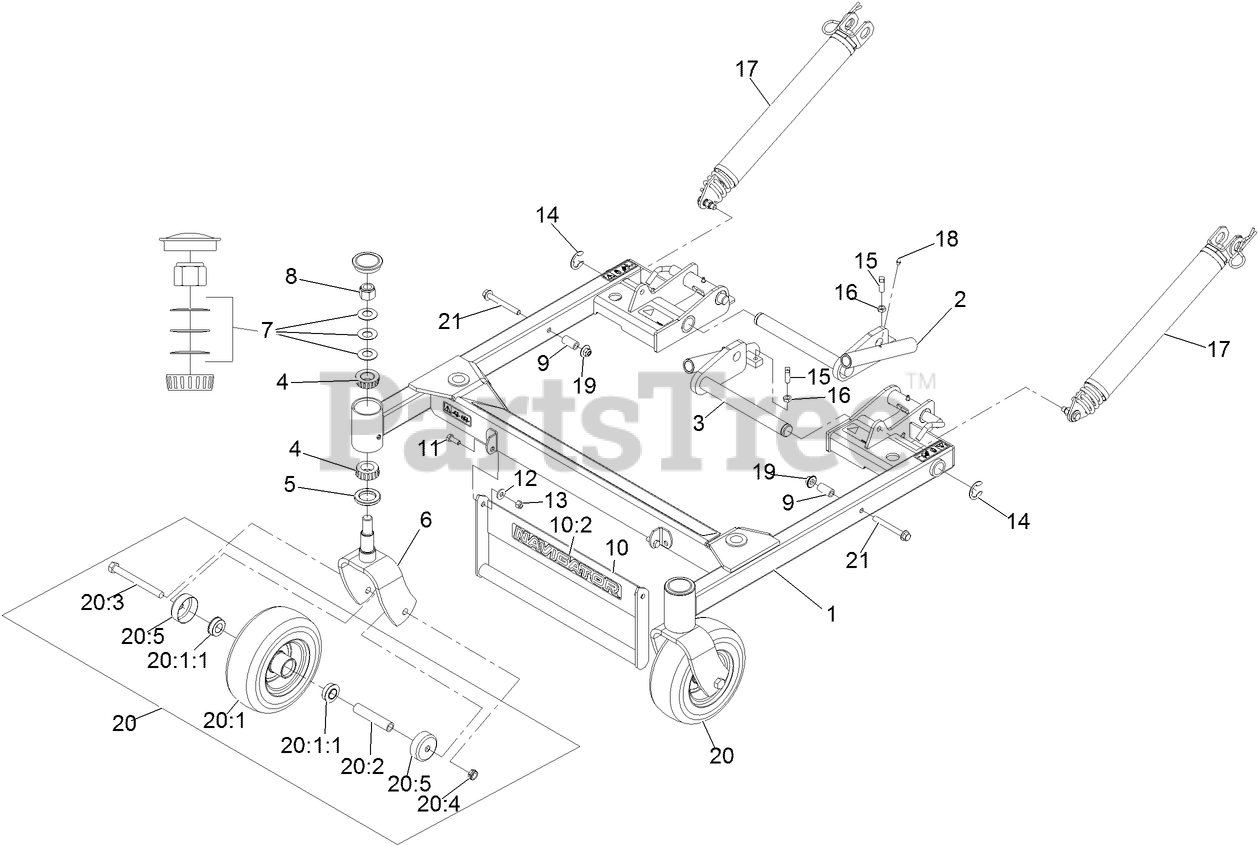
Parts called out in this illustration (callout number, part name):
1	Frame-Deck Support W/Decals
2	PIVOT-DECK, RH
3	PIVOT-DECK, LH
4	Cone-Bearing Tapered Roller
5	SEAL-GREASE
6	FORK-CASTER
7	WASHER-BELLVILLE
8	NUT-LOCK, NI
10	ASM,DECK LIFT HANDLE W/DECAL
10:2	DECAL-NAVIGATOR LOGO
11	SCREW-HH
12	WASHER-SPRING
13	NUT-LOCK, NI
14	RING-SNAP
15	SCREW-SET, SQH
16	NUT-JAM
17	LIFT ASSIST SPRING ASM
18	FITTING-GREASE
19	Nut-Nyloc 3/8-16 Flg
20	ASM,FF CASTER WHEEL W/AXLE
20:1	ASM,WHEEL AND TIRE
20:1:1	Bearing-Ball
20:2	SPACER-CASTER, FRONT
20:3	SCREW-HH
20:4	NUT-HEX
20:5	GUARD-SEAL
21	Screw-HHF
